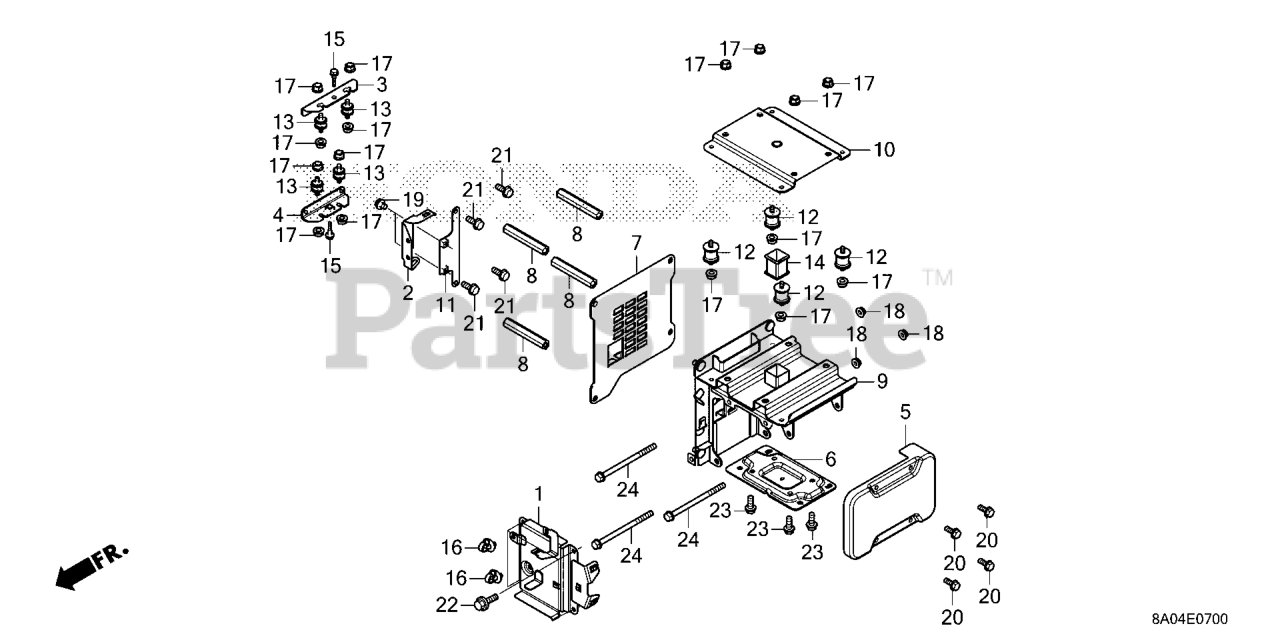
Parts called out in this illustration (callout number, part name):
1	BRACKET A, HARNESS
2	BRACKET B, HARNESS
3	STAY A, PDU
4	STAY B, PDU
5	FRAME, SIDE *NH1*
6	BASE, MOTOR *NH105*
7	STAY C, PDU
8	COLLAR, SPECIAL
10	FRAME, BATTERY
11	STAY, BRACKET
12	RUB, BATTERY MOUNT
13	RUBBER, MOUNT
14	RUBBER A, STOPPER
15	BOLT, STOPPER (6X25)
16	CLIP, HARNESS BAND (145MM) (BLACK)
17	NUT, FLANGE (6MM)
18	NUT, FLANGE (8MM)
19	BOLT, FLANGE (6X10)
20	BOLT, FLANGE (6X16)
21	BOLT, FLANGE (6X16)
22	BOLT, FLANGE (6X20)
23	BOLT, FLANGE (8X20)
24	BOLT, FLANGE (8X125)
